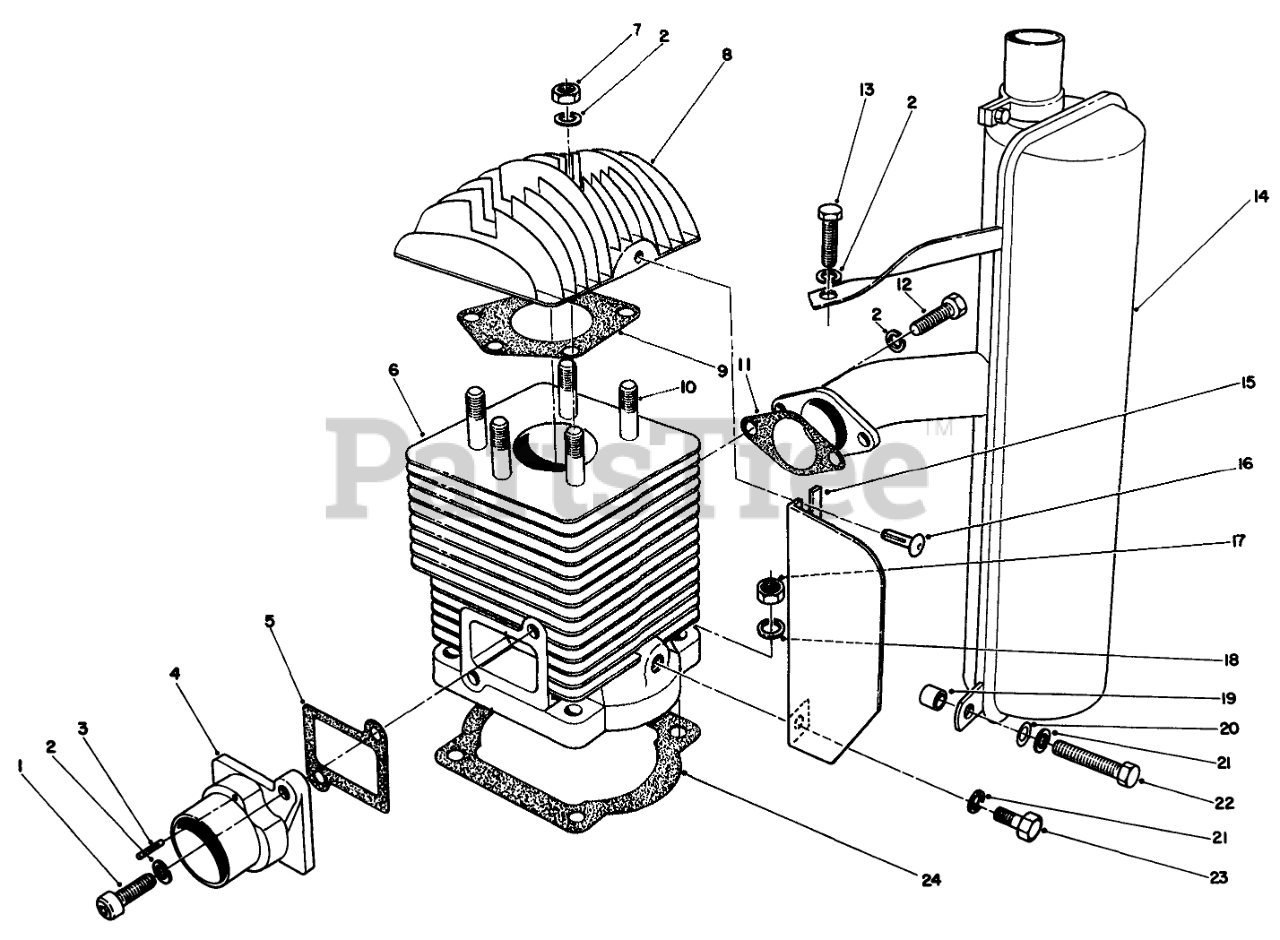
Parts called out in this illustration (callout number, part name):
1	Capscrew-Socket Head
2	Lockwasher
3	Pin-Wrist
4	Manifold-Carburetor
5	Gasket
6	Cylinder
8	Cylinder Head
9	CYL. HEAD GASKET
11	Gasket
12	Screw-Hex Head
13	Screw-Hex Head
14	Muffler
15	Air Guide Kit (Incl. Ref. #19, 22-24)
16	Rivet
18	Lockwasher
19	Spacer-Tube
20	Washer
21	Lockwasher
22	Screw-Hex Head
23	Capscrew-Hex Head
24	Gasket
